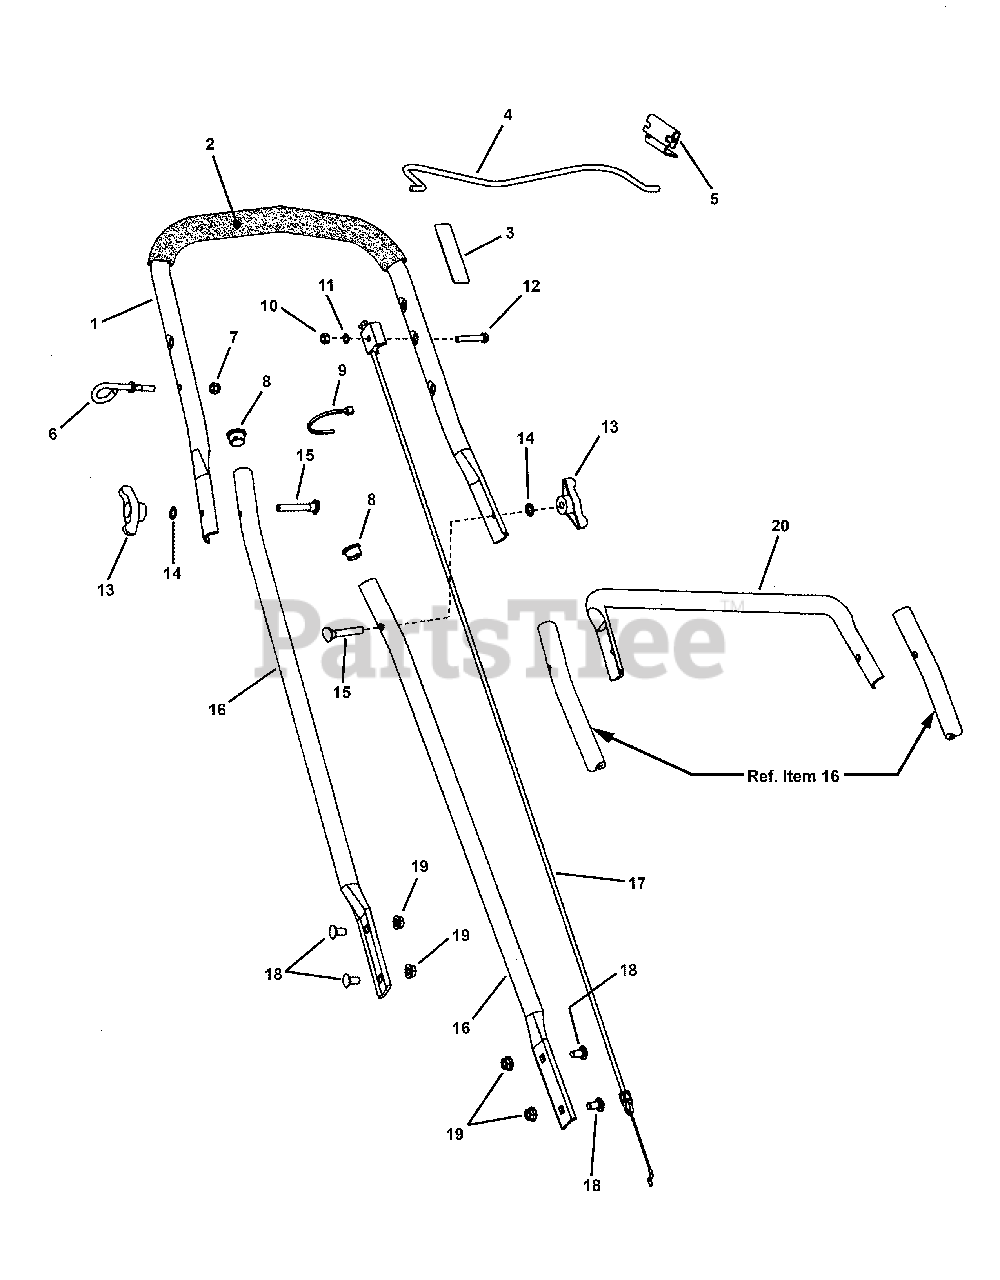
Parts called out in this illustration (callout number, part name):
1	HANDLE, Upper
2	GRIP, Foam Yellow 10.75" long
2	GRIP, Foam Black 12" long
3	DECAL, Blade Control
4	BAIL, OPC Control
5	CLIP, Zone Control
6	GUIDE, ROPE (1/4-20 threads)
7	NUT, 1/4-20 Hex Nyloc
8	PLUG, Trans
9	WIRE TIE, Black 1.29" long
10	NUT, 1/4-20 Hex
11	WASHER, 1/4" Internal Tooth Lock
12	SCREW, 1/4-20 x 1-1/2" Hex Head Cap, GR 5
13	KNOB, 5/16-18 Wing (Black)
14	WASHER, 5/16" Internal Tooth Lock
15	BOLT, 5/16-18 x 2" Curved Head
16	HANDLE, Middle-1992
17	CABLE, Blade Control
17	CABLE, OPC 19S/21S NH, B&S
18	BOLT, 5/16-18 x 5/8" Short Neck Carriage, GR 5
19	NUT, 5/16-18 Hex Flange Lock, GR 5
20	CROSS BAR
